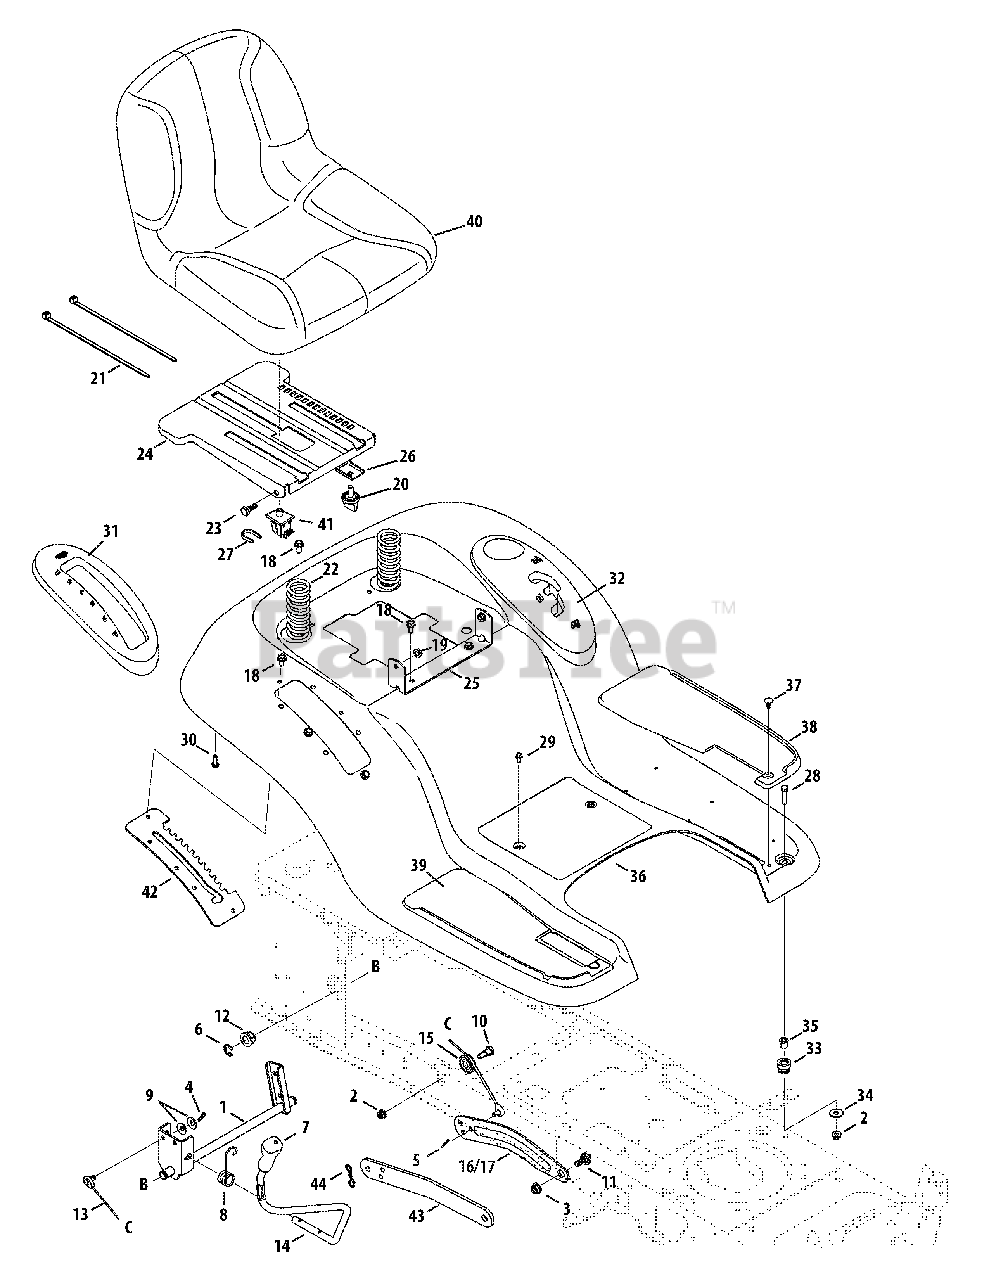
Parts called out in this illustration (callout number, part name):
1	Shaft Ass’y, Lift
2	Nut, Flange Lock, 5/16-18, Grf
3	Nut, Flange Lock, 3/8-16, Grf
4	Pin, Cotter, .072 Dia. x 1.13
5	Pin, Cotter, Bow-Tie 72
6	Ring, E Type, .625 Dia. Shaft
7	Grip, Handle, 1/2
8	Spring, Torsion
9	Washer, Spring, .401 x .870 x .063
10	Screw, Shoulder, .437 x .470, 5/16-18
11	Bolt, Shoulder, .500, 3/8-16 (46")
12	Bearing, Hex Flange
13	Cable, Lift, 16.16
14	Handle, Lift,
15	Pulley, Roller, Cable
16	Arm, Lift, 42" Rt RH
17	Arm, Lift, 42" Rt LH
18	Screw, Self-tapping, 5/16-18, .750,
19	Nut, Flange Lock, 5/16-18, Gr5, Sd Lk
20	Knob, 3/8-16, .875
21	Cable, Tie, 3/16 x .05 x 7.4
22	Spring, Comprs, 1.71 x 3.735 x .238
23	Screw, Shoulder, .437 x .268, 5/16-18
24	Bracket, Mounting, Seat
25	Bracket, Pivot, Seat
26	Bracket, Knob Adjustment, Seat
27	Clip, Retaining, Switch
28	Hex Screw, 5/16-18, 1.25, Gr5, Std
29	Screw, Self-tapping, 1/4-20, 0.500,
30	Screw, HL, 1/4-15, 0.750,
31	Cover, Lift Lever
32	Cover, Shaft, w/ Cup Holder
33	Grommet, .4375 ID x .750
34	Washer, Flat .344 x 1.00 x .063
35	Spacer, Flange, .3125 x .4375 x .625
37	Clip, Ratchet, .250 Dia
38	Pad, Foot, LH
39	Pad, Foot, RH
40	Seat, High Back
41	Switch, Seat
42	Bracket, Lift, Man PTO, 6 Pos
43	Link, Lift (46" Decks)
44	Pin, Cotter, Bow-Tie 72 (46" Decks)
